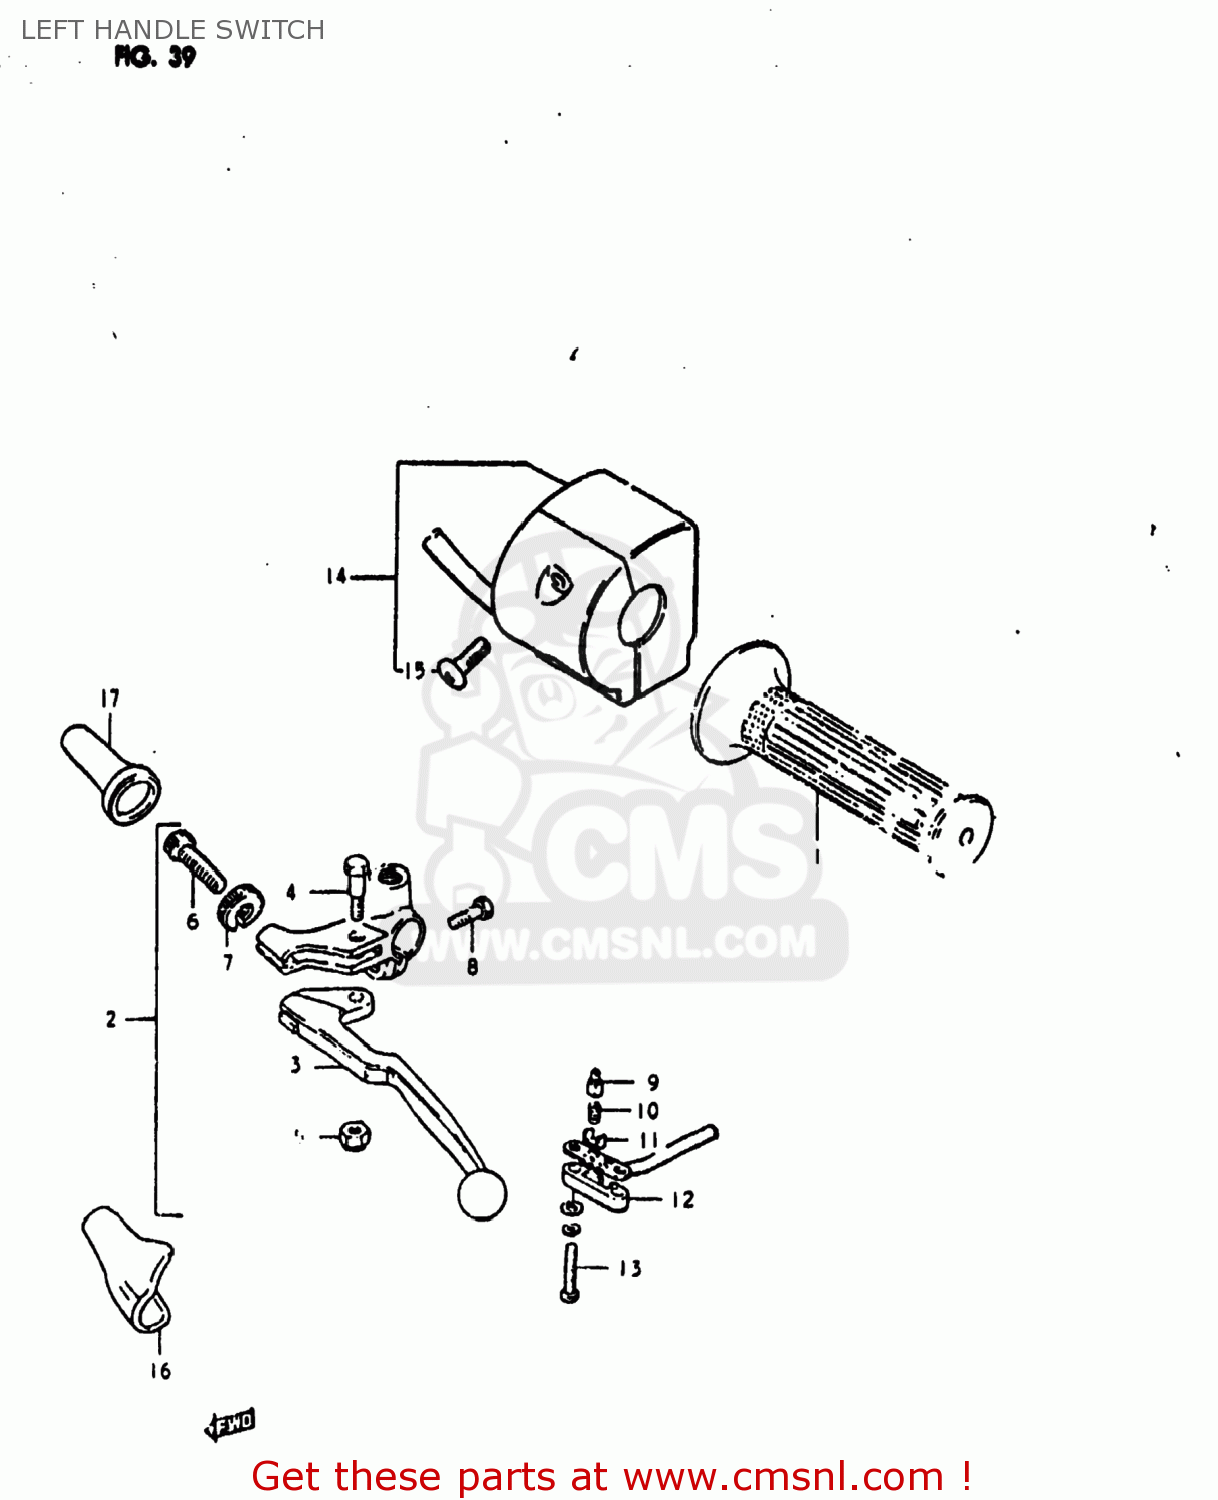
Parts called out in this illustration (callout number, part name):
1	GRIP,LEFT
2	LEVER ASSEMBLY
3	LEVER,CLUTCH
4	BOLT,LEVER
5	NUT 6MM
6	ADJUSTER,CABLE
7	NUT,CABLE ADJUSTER
8	BOLT,CLUTCH LEVER HOLDER
9	HOLDER
10	SPRING
11	PLATE
12	COVER,FR BK TERMINAL BASE
13	SCREW
14	SWITCH ASSEMBLY,HANDLE,LEFT
15	SCREW
16	COVER,CLUTCH LEVER
